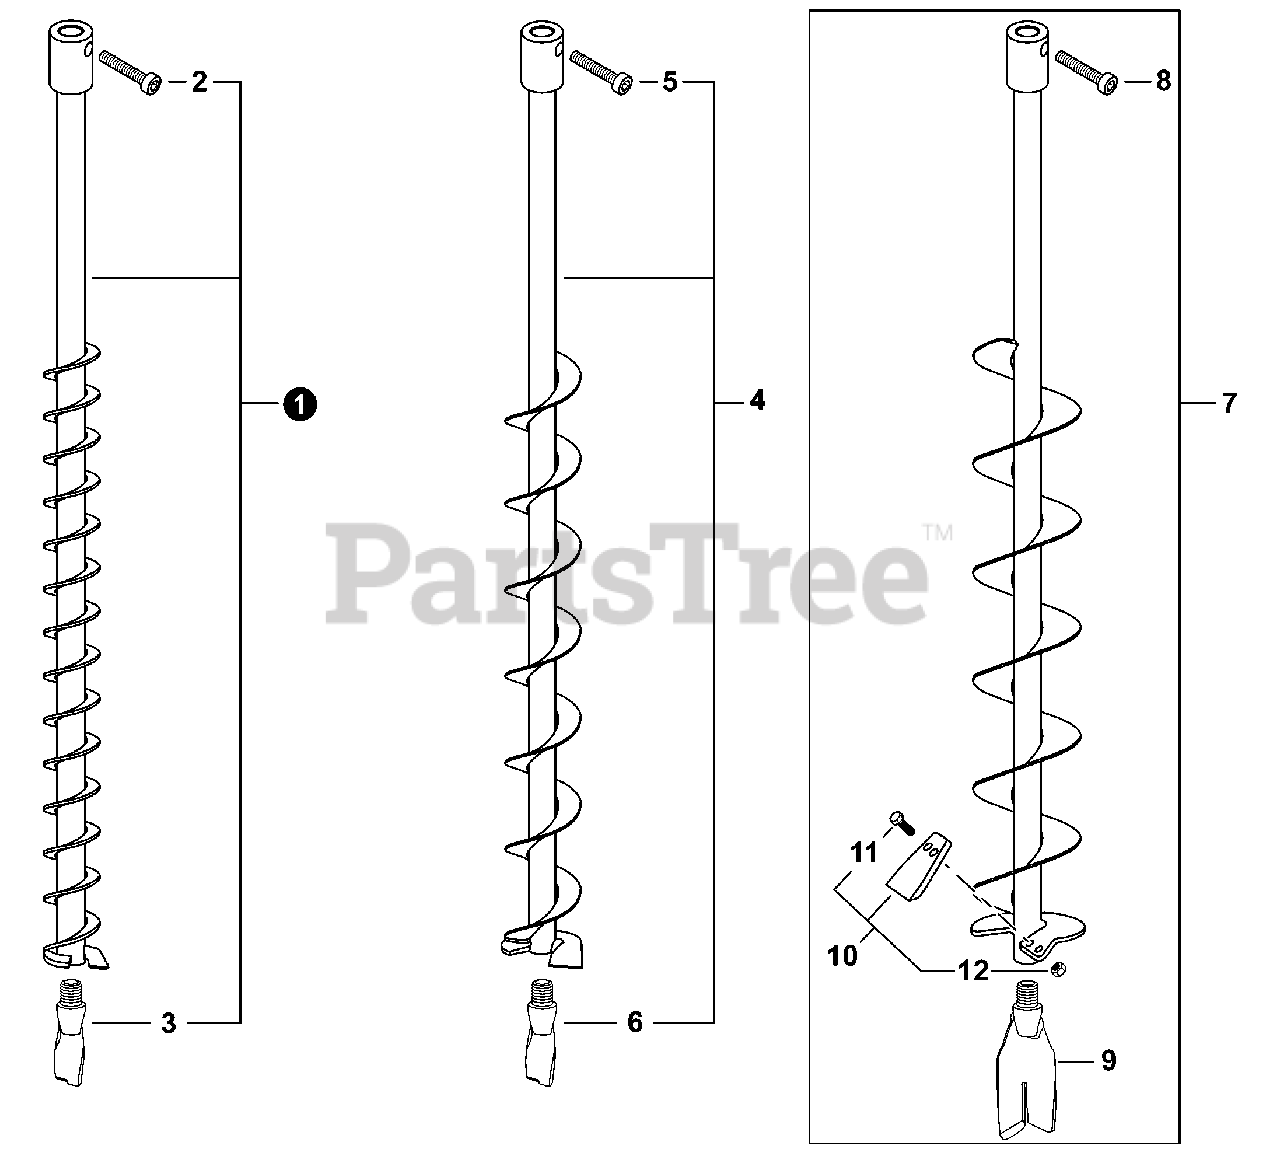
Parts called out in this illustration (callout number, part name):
1	EARTH AUGER W/POINT - 2" DIA.
2	BOLT 3/8"-16×1-1/4"
3	EARTH AUGER POINT - 1" DIA.
4	EARTH AUGER W/POINT - 3" DIA.
5	BOLT 3/8"-16×1-1/4"
6	EARTH AUGER POINT - 1" DIA.
7	EARTH AUGER W/POINT - 4" DIA.
8	BOLT 3/8"-16×1-1/4"
9	EARTH AUGER POINT - 2" DIA.
10	EARTH AUGER BLADE KIT - 4" DIA.
